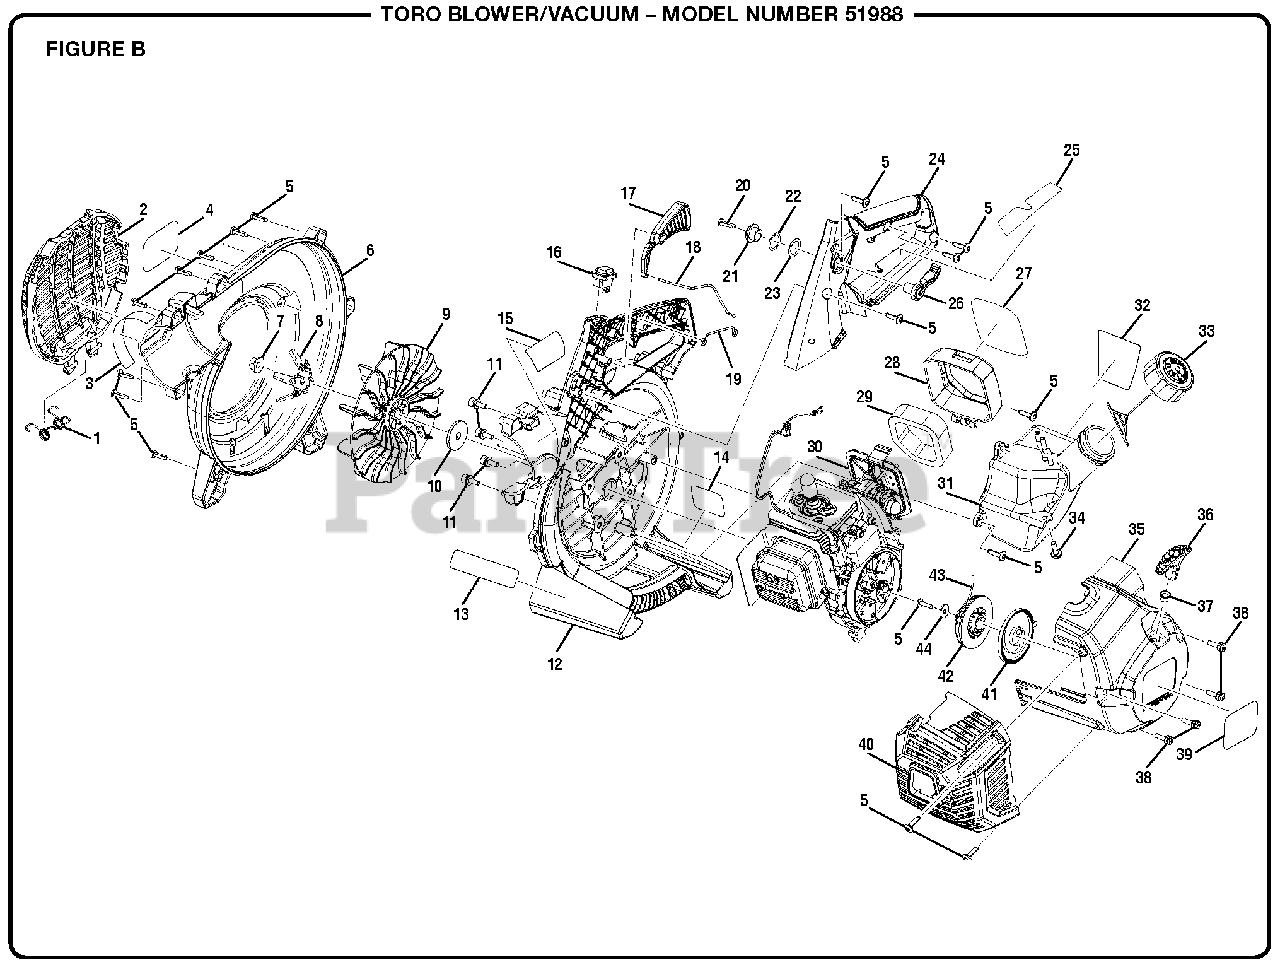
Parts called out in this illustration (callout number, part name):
1	Vacuum Door Hinge
2	Vacuum Door
3	Warning Icon Label
4	Logo Label (Right)
5	Screw (10-14 x 3/4 in.)
6	Outer Volute Assembly
7	Flanged Lock Nut (M8 x 1.25, LH)
8	Mulching Blade
9	Blower Fan
10	Washer (ID8 x OD34 x 3t)
11	Screw (M5 x 16mm, Torx Pan Hd.)
12	Engine Shroud Assembly
13	Combustion Warning Label
14	Logo Label (Rear)
15	Tube Removal Label
17	Throttle Lever
18	Throttle Cable Assembly
19	Ground Wire Assembly
20	Screw (10-14 x 3/4 in., T25 Torx Hd. T.F.)
21	Throttle Trigger Activator
22	Wavy Washer (21.7OD x 16.5ID)
23	Washer (22.5OD x 16ID x 0.5t)
24	Handle Cover Assembly
25	Icon Warning Strip
26	Cruise Control Lever
27	Starting Instructions Label
28	Air Box Cover Assembly
29	Air Filter
30	Power Head Assembly
31	Fuel Tank Assembly
32	E85 Label
34	Screw (M5 x 16 mm)
35	Starter Housing Assembly
36	Starter Grip
38	Screw (M5 x 20 mm, Torx Pan Hd.)
39	Logo Label (Left)
40	Muffler Cover
41	Spring Holder Assembly
42	Starter Pulley
43	Starter Rope
44	Washer (ID6.2 x OD18 x 1.5t)
